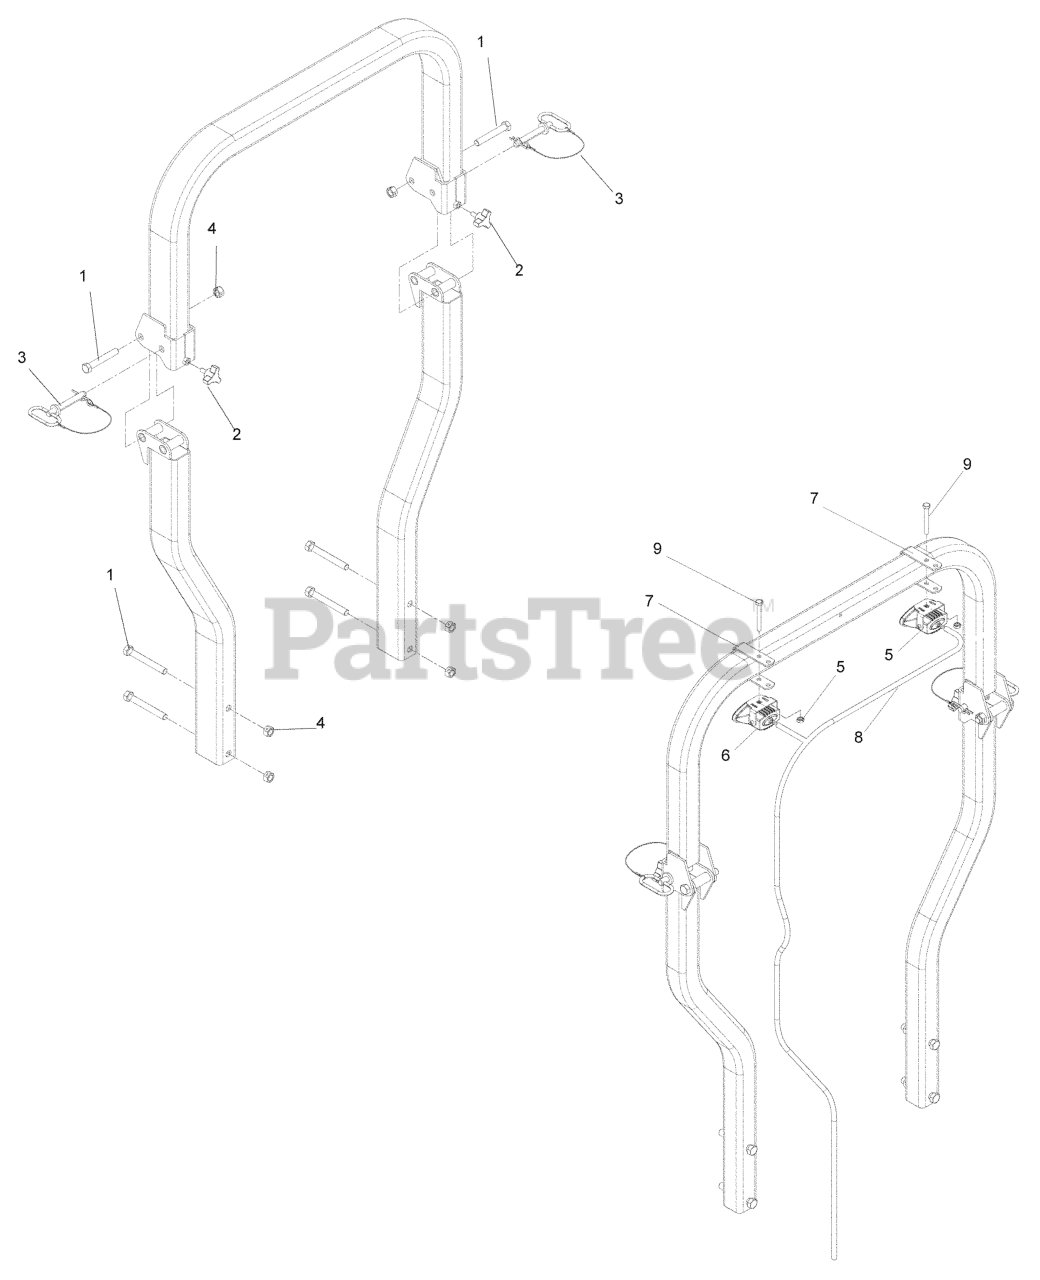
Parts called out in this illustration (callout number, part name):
1	HCS 1/2C X 3 1/4
2	KNOB W/STUD
3	PIN, 1/2" W/LANYARD
4	NUT 1/2-13 HEX CNTRLK GR 5 ZD
5	NUT 5/16-18 HEX JAM ZD
6	LIGHT 35W W/BRKT
7	LIGHT MOUNTING BRACKET
8	LIGHT HARNESS
9	BOLT 5/16C X 2 1/2
